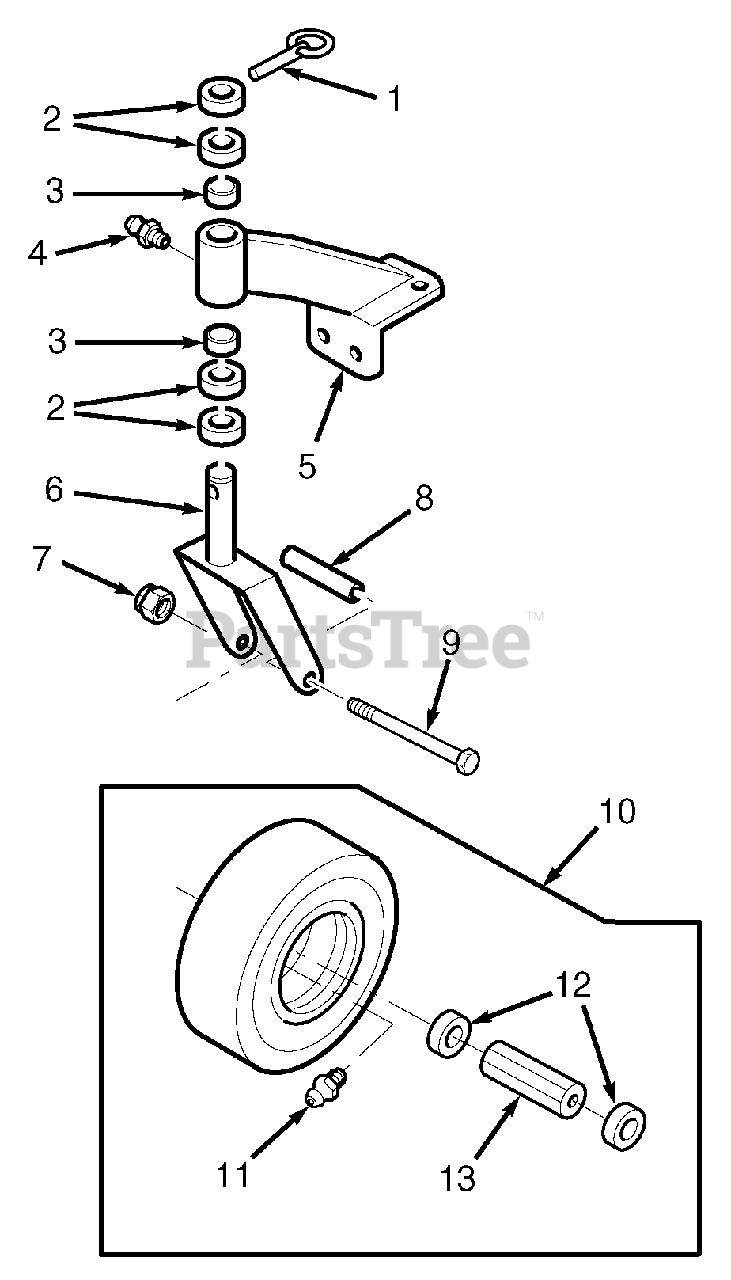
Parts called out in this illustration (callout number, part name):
1	Quick Pin
2	Spacer, Caster Yoke, 1/2" Long
3	Bronze Bearing
4	Grease Fitting
5	Support Assembly
6	Caster Yoke
7	Elastic Stop Nut, 1/2-13
8	Sleeve, Caster Wheel Bearing
9	Hex Hd. Bolt, 1/3-13 x 5-1/2"
10	Flat Free Tire Assy.
11	Grease Fitting, 45 Degree 1/4-28
12	Retainer, Bearing, Caster Wheel
13	Roller Bearing, Caster Wheel
